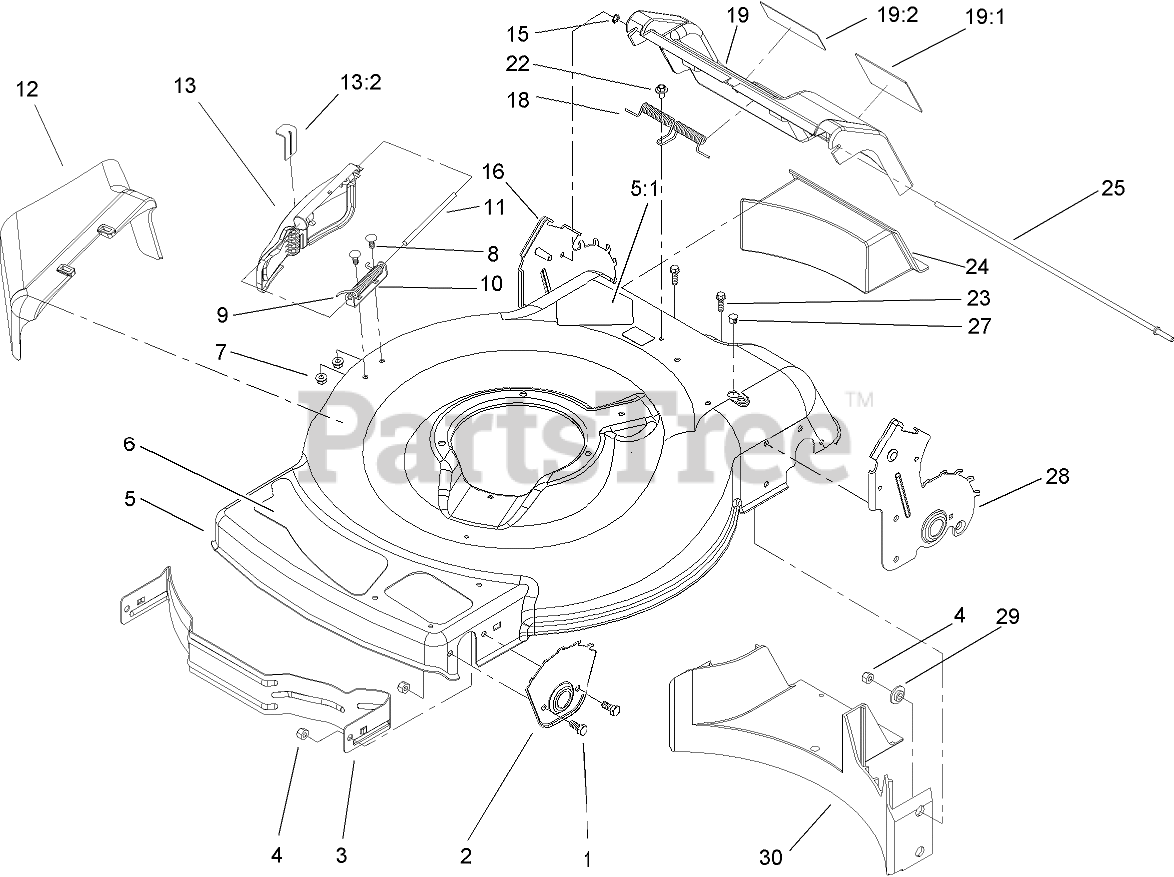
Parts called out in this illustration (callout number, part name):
1	SCREW-HH
2	Plate-HOC, Front
3	Baffle-Front
4	NUT-LOCK, NI
5	HOUSING (only on: 20018)
5	HOUSING (only on: 20014)
5:1	DECAL-DANGER (only on: 20018)
5:1	DECAL-DANGER, CUT FINGER (only on: 20014)
6	Decal-Deck
7	NUT-HHF
8	SCREW-CARR
9	SPRING-TORSION
10	BRACKET-COVER
11	ROD-COVER
12	CHUTE-DISCHARGE, SIDE
13	DOOR-DISCHARGE ASM
13:2	LEVER-LATCH
15	NUT-PUSH
16	RH REAR HOC PLATE ASM (only on: 20014)
16	RH REAR HOC PLATE ASM (only on: 20018)
18	Spring-Door, Rear
19	DOOR (only on: 20018)
19	DOOR (only on: 20014)
19:1	DECAL-WARNING (only on: 20014)
19:2	DECAL-WARNING (only on: 20014)
19:2	DECAL-WARNING (only on: 20018)
22	SCREW AND WASHER ASM
23	SCREW-HWH
24	Plug-Discharge, Rear
25	Rod-Pivot, Rear Door
27	Plug-Dome
28	LH REAR HOC PLATE ASM (only on: 20014)
28	LH REAR HOC PLATE ASM (only on: 20018)
29	Washer-Stepped
30	Baffle-Rear
